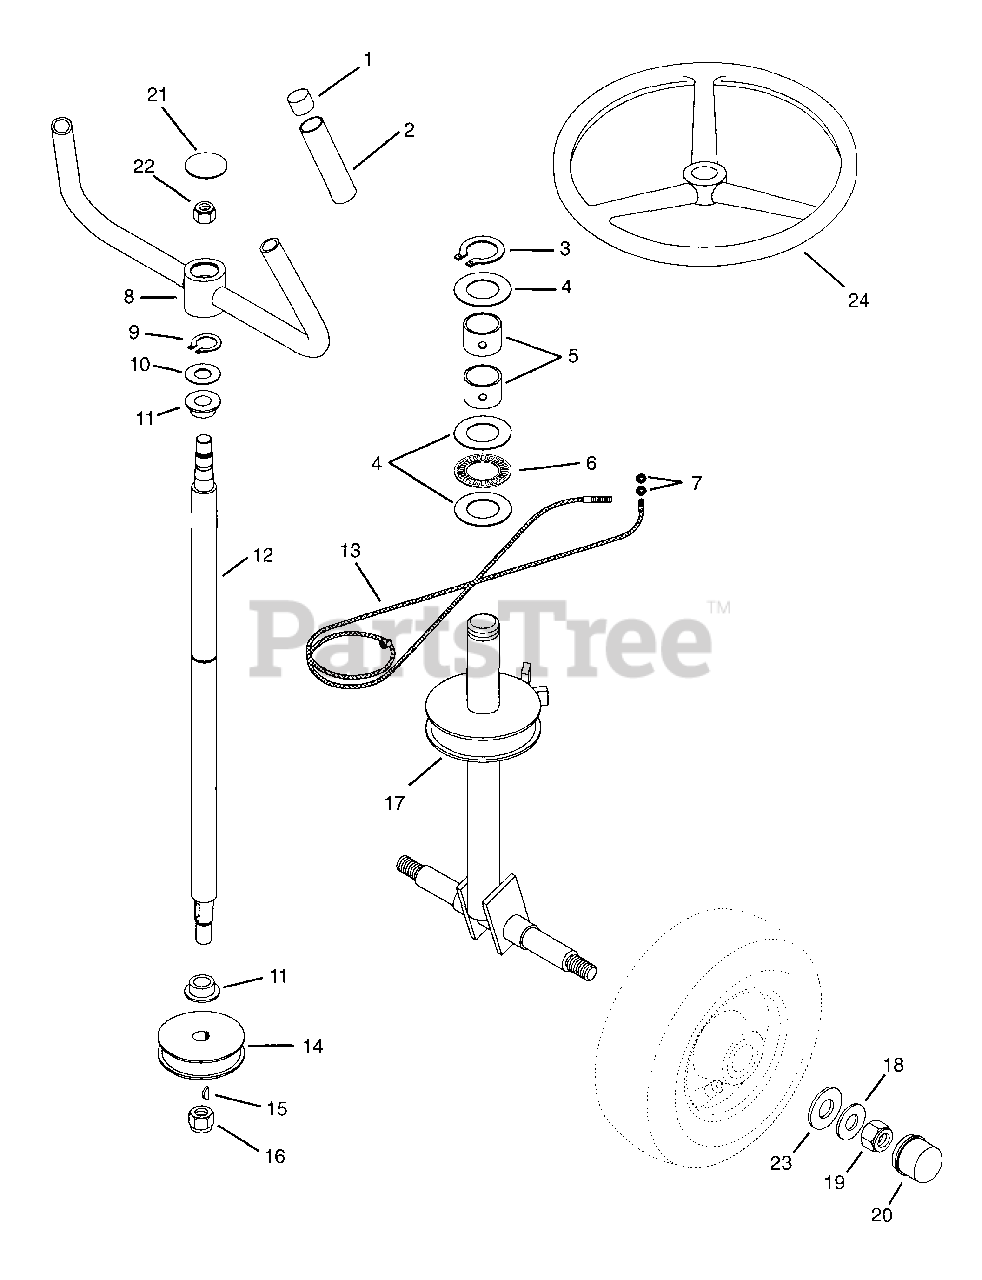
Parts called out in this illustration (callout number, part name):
1	Closure-Vinyl
2	Grip
3	Ring-Retaining-External 1.5 x 1.38
4	Washer-Thrust 1.502 x 2.18 x .063
5	Bearing 1.000 x 1.135 x 1.002
6	Bearing-Needle-Thrust 1.50 x 2.187 x .0781
7	Nut-Jam .312-18
8	Weldment, Handlebar
9	Ring-Retaining-External .906 x .078
10	Washer-Thrust 1.55 x 1.002 x .093
11	Bushing-Flange 1.020 x 1.385 x .75 x 1.75
12	Shaft-Steering
13	Cable-Steering
14	Pulley-Cable
15	Key-Woodruff 3/16 x 7/8
16	Nut-Locking 5/8-11
17	Weldment-Caster Wheel
18	Washer-Flat .812 x 1.469 x .134
19	Nut-Locking-Center .62 x - 11
20	Cap-Dust
21	Closure-Vinyl
22	Nut-Hex .62-11
23	Washer-Hardened-Thrust 1.00 x 1.55 x .03
24	Steering Wheel
